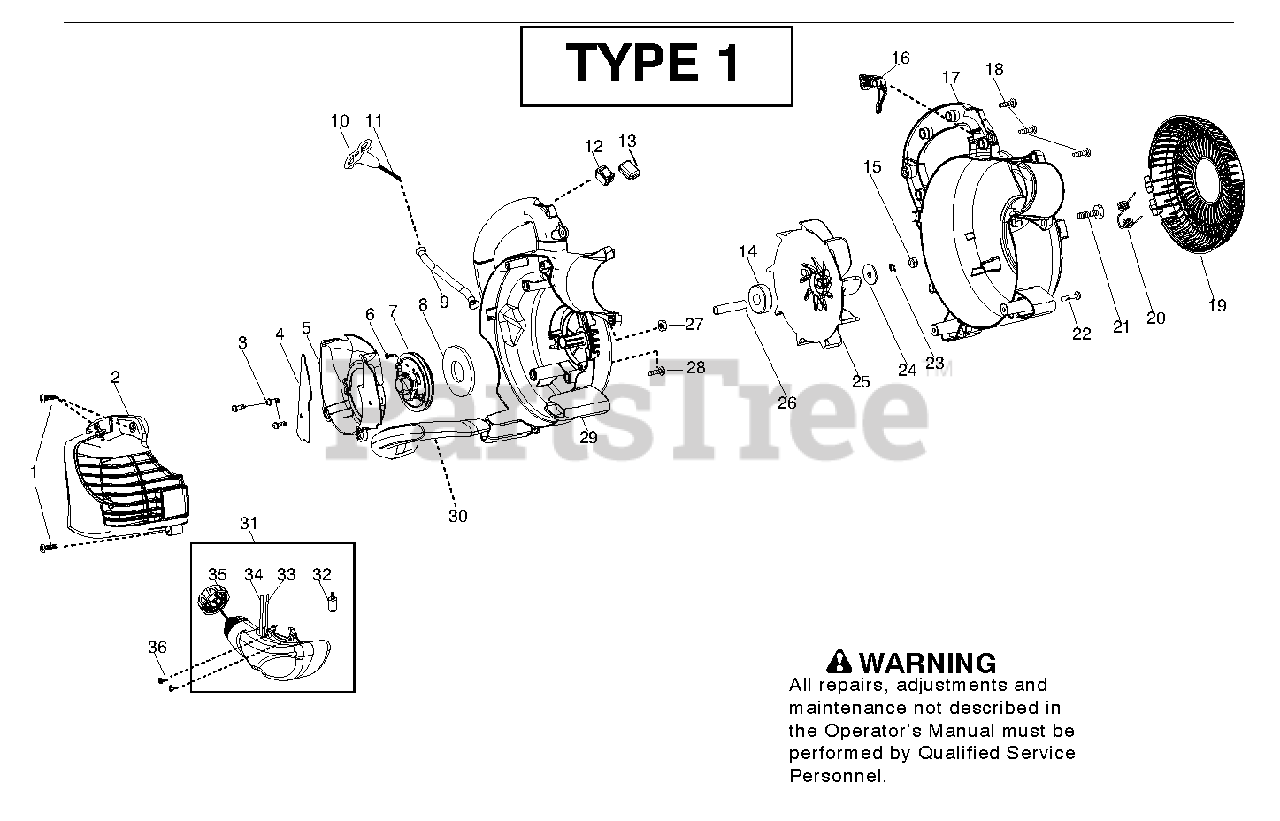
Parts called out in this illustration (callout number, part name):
2	ASSY COVER ENGINE
4	SHIELD BAFFLE
6	SCREW SEMS TOOTHED WASHER
7	KIT STARTER PULLEY
8	KIT STARTER SPRING
9	TUBE STARTER ROPE
10	HANDLE STARTER BLK
12	KIT SWITCH
13	PROTECTOR, SWITCH
16	TRIGGER THROTTLE RED
17	COVER
19	DOOR VAC BLACK
20	SPRING VAC DOOR
22	SCREW #10 PLASTITE 1.362
24	WASHER, IMPELLER
25	ASSY IMPELLAR HUB
26	SPACER FLYWHEEL
29	FAN HOUSING
30	HANDLE VAC BLACK
31	Fuel Tank Assembly, Non Low Perm St
32	FUEL PICK-UP ASSY
35	ASSY FUEL CAP W/RETAINER
36	SCREW FUEL TANK RETAINER
